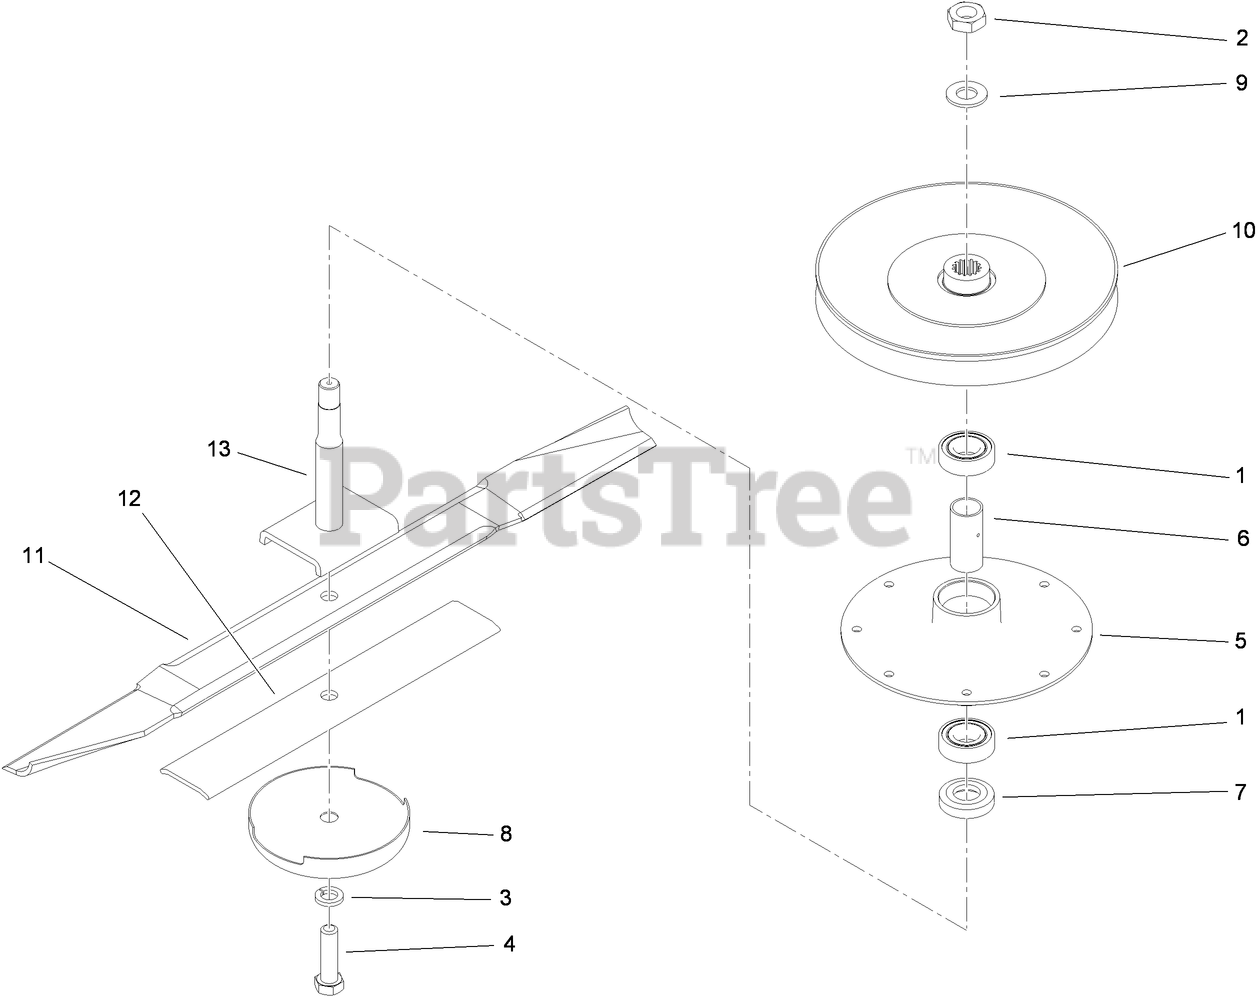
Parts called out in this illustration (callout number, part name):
1	BEARING-BALL
2	NUT-HEX
3	WASHER-LOCK/SP
4	SCREW-BLADE
5	HOUSING-SPINDLE
6	SPACER-BEARING
7	SPACER
8	CUP-SCALP, ANTI
9	Washer-Pinion
10	PULLEY ASM
11	BLADE-RECYCLER
12	SPACER-BLADE
13	SPINDLE SHAFT ASM
